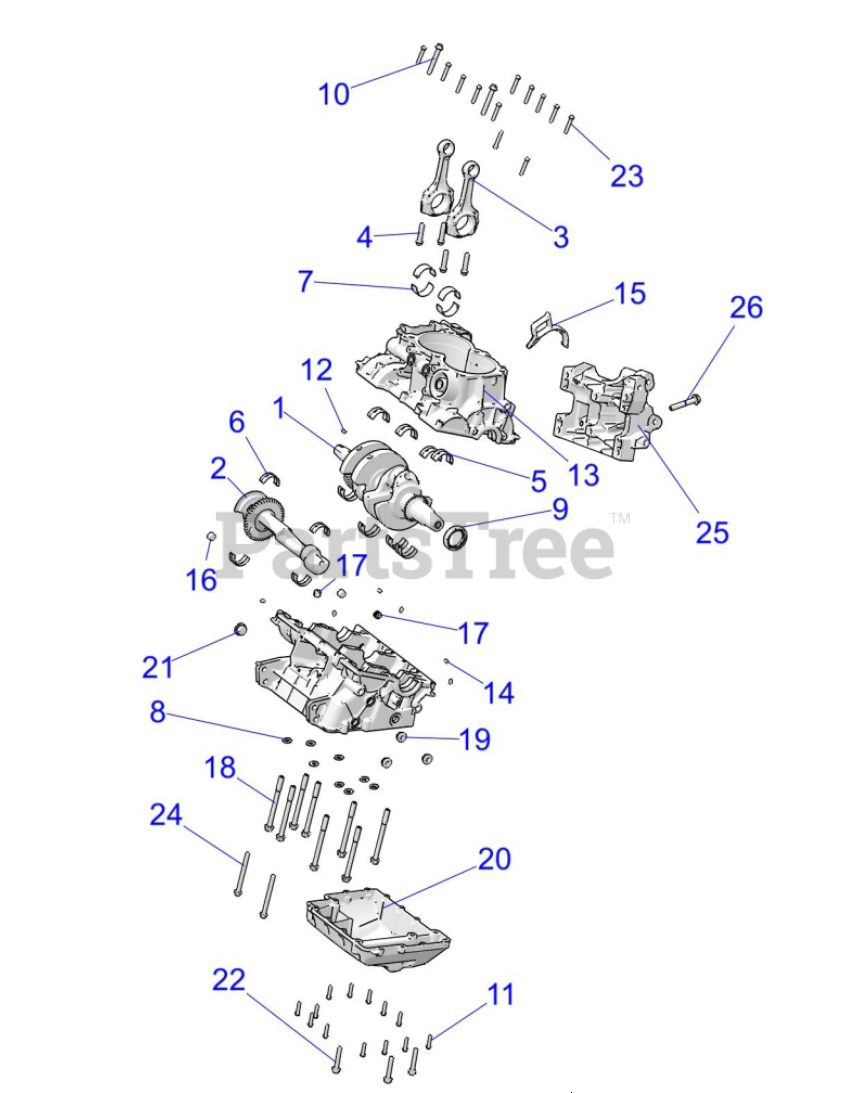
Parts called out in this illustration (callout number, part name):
1	ASM-CRANKSHAFT
2	ASM., BALANCE SHAFT
3	ASM-CONNECTING ROD
4	SCR-ROD,MJ9X1X40-4H6H,12.9
5	BEARING, MAIN, BLUE
5	BEARING, MAIN, GREEN
5	BEARING, MAIN, YELLOW
5	BEARING, MAIN, RED
6	BEARING, CONNECTING ROD, WHITE
6	BEARING, CONNECTING ROD, BLUE
6	BEARING, CONNECTING ROD, GREEN
6	BEARING, CONNECTING ROD, YELLOW
7	BEARING, BALANCE SHAFT
9	SEAL-CRANKSHAFT
10	SCR-HXFLG,M8X1.25X60
11	SCR-HXFLG,M6X1.0X25,10.9
12	KEY,WOODRUFF
13	KIT, CRANKCASE
14	PIN, DOWEL
15	DIVERTER, OIL DRAIN
16	PLUG-3/8 NPT,HX/SOC W/SEALANT
17	PLUG-HEX SOCKET,1/4X18,SEALANT
19	PLUG-HEX SCKT,W/O-RING,M16X1.5
20	COVER, SUMP
21	PLUG-HEX SCKT,W/O-RING,M20X1.5
22	SCR-M8X1.25X50 HX/FL-Y
23	SCR-HXFL-M6X1.0X35 8.8 ZY3
24	SCR-HXFLG,M8X1.25X90
25	BRKT-TRANSJOINT,MACH
26	BOLT-M10X1.5X60MM8.8HEXDRILOCK
